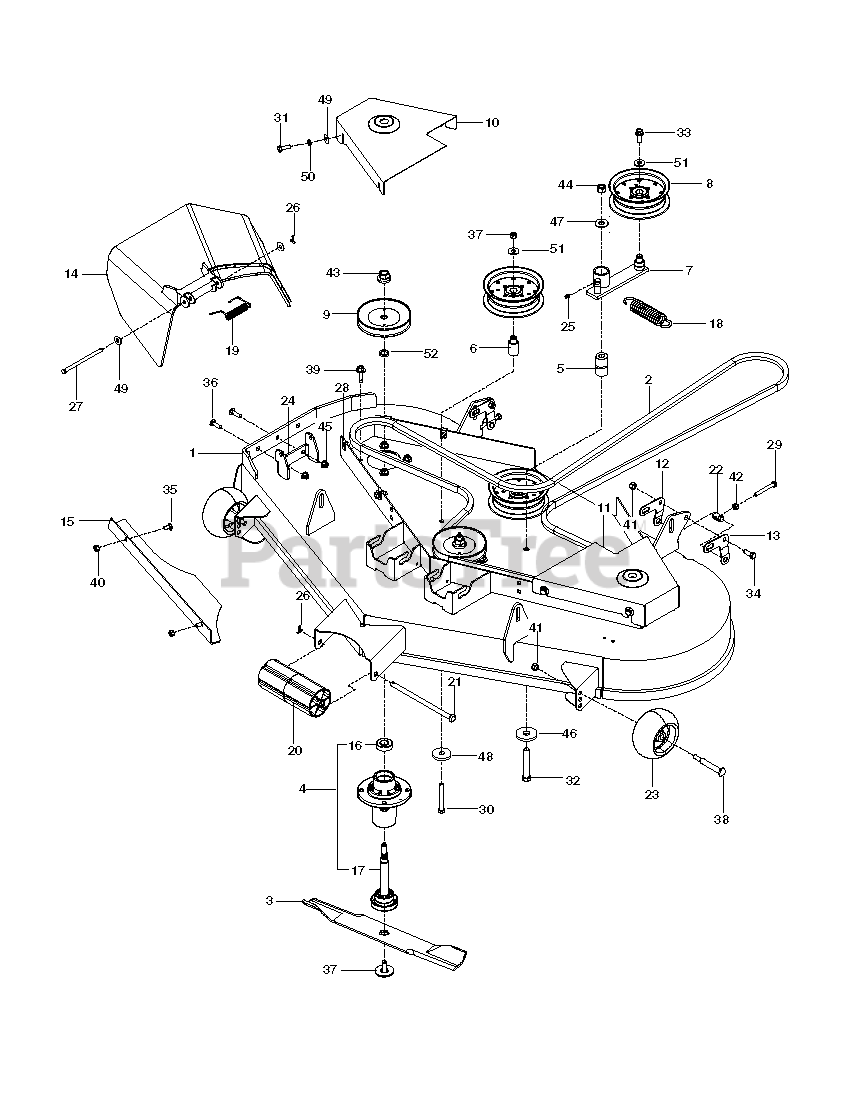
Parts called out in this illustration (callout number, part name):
1	DECK MZT 52 W/SFTY DECALS.ORNG
2	BELT, B, 148.5
3	BLADE, 18"
4	MANDREL.DECK.ASSEMBLY
5	PIVOT BUSHING
6	IDLER BUSHING
8	PULLEY, IDLER
9	PULLEY MANDREL
10	BELT SHIELD, RIGHT 52, ORG
11	BELT SHIELD, LEFT 52, ORG
12	BRACKET.RT.PNT.MS431
13	BRACKET.LH.PNT.MS431
14	DISCHARGE CHUTE 52"
15	CONFINEMENT PLATE, 52"
16	BEARING, BALL
17	SHAFT ASM MANDREL
19	SPRING - TORSION
20	NOSE ROLLER 48"
21	ROD.ROLLER.NOSE.NARROW.48"
22	TRUNION, PITCH
23	GAUGE WHEEL
24	BRACKET MZ CHUTE
25	ZERK
26	RP_COTTER PIN 1/8 X 3/4
27	PIN-CLEVIS 5/16 DIA X 5.19 ZD
28	U-CLIP 5/16-18 NUT RETAINER
29	HCS 5/16-18 X 2 1/2 TPBLT
30	HCS 3/8C X 3
31	HCS 5/16C X 1
32	HCS 1/2C X 3 1/4
33	4CS 3/8C X 1 SERRATED HEAD
34	HCS 3/8-16X1.GRD.5.ZD
35	CARRIAGE BOLT 5/16C X 5/8"
36	RHSSNB 5/16C X 1.0
37	BLADE BOLT ASSY-7/16" TB REPL
38	BOLT, SHOULDER
39	SCREW, WASHER HEAD
40	NUT 5/16 NYLOC
41	NUT 3/8-16 NYLOC
42	NUT 5/16C HEX
43	LOCKNUT - 9/16
44	RP NUT 1/2-13 HEX NYLOC ZD
45	5/16-18 NYLOC FLANGE NUT
46	WASHER, SUPPORT
47	WASHER 1/2 FLAT
48	SPINDLE WASHER
49	WASHER 5/16 FLAT
50	WASHER 5/16 LOCK
51	RP WASHER 3/8 FLAT
52	WASHER-SPACER
